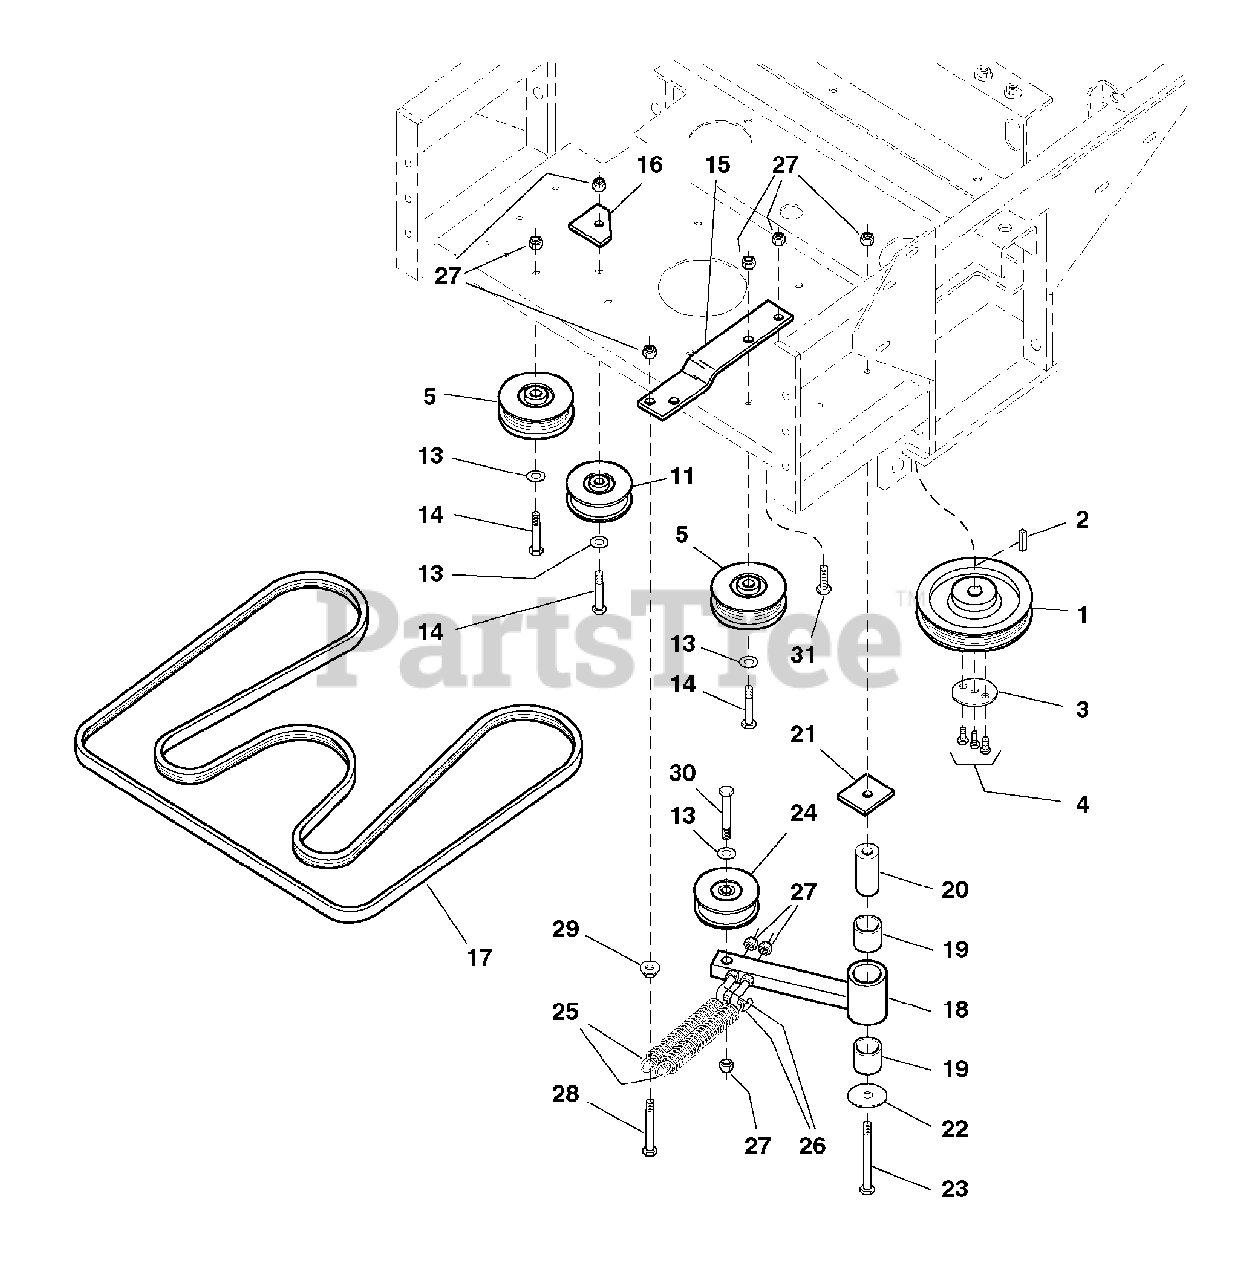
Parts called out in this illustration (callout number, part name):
1	PULLEY, Pump Drive
2	KEY, 5mm x 25mm
3	RETAINER, Pulley
4	CAPSCREW, Hex Hd, M6 x 10mm
5	IDLER PULLEY ASSEMBLY, Complete (includes Ref 6, 7, 8, 9 & 10)
11	IDLER PULLEY ASSEMBLY, Complete (includes Ref 6, 7, 8, 9 & 12)
13	WASHER, 3/8
14	CAPSCREW, Hex Hd, 3-8-16 x 2-1/4
15	SPRING ANCHOR
16	PULLEY SUPPORT
17	BELT, Grooved
18	IDLER ARM ASSEMBLY, Complete (includes Ref 19)
19	BUSHING, Brass
20	SHAFT, Idler Pivot
21	SPACER, Idler Pivot
22	RETAINER, Idler Arm
23	CAPSCREW, Hex Hd, 3/8-16 x 4
24	IDLER PULLEY ASSEMBLY, Complete (incudes Ref 6, 7, 8, 9 & 12)
25	SPRING, Extension
26	SCREW HOOK
27	NUT, Hex, Nylon Lock, 3/8-16
28	CAPSCREW, Hex Hd, 3/8-16 x 2-1/2
29	NUT, Hex, Serrated Flange, 3/8-16
30	CAPSCREW, Hex Hd, 3/8-16 x 2-3/4
31	CAPSCREW, Hex Hd, 3/8-16 x 1
